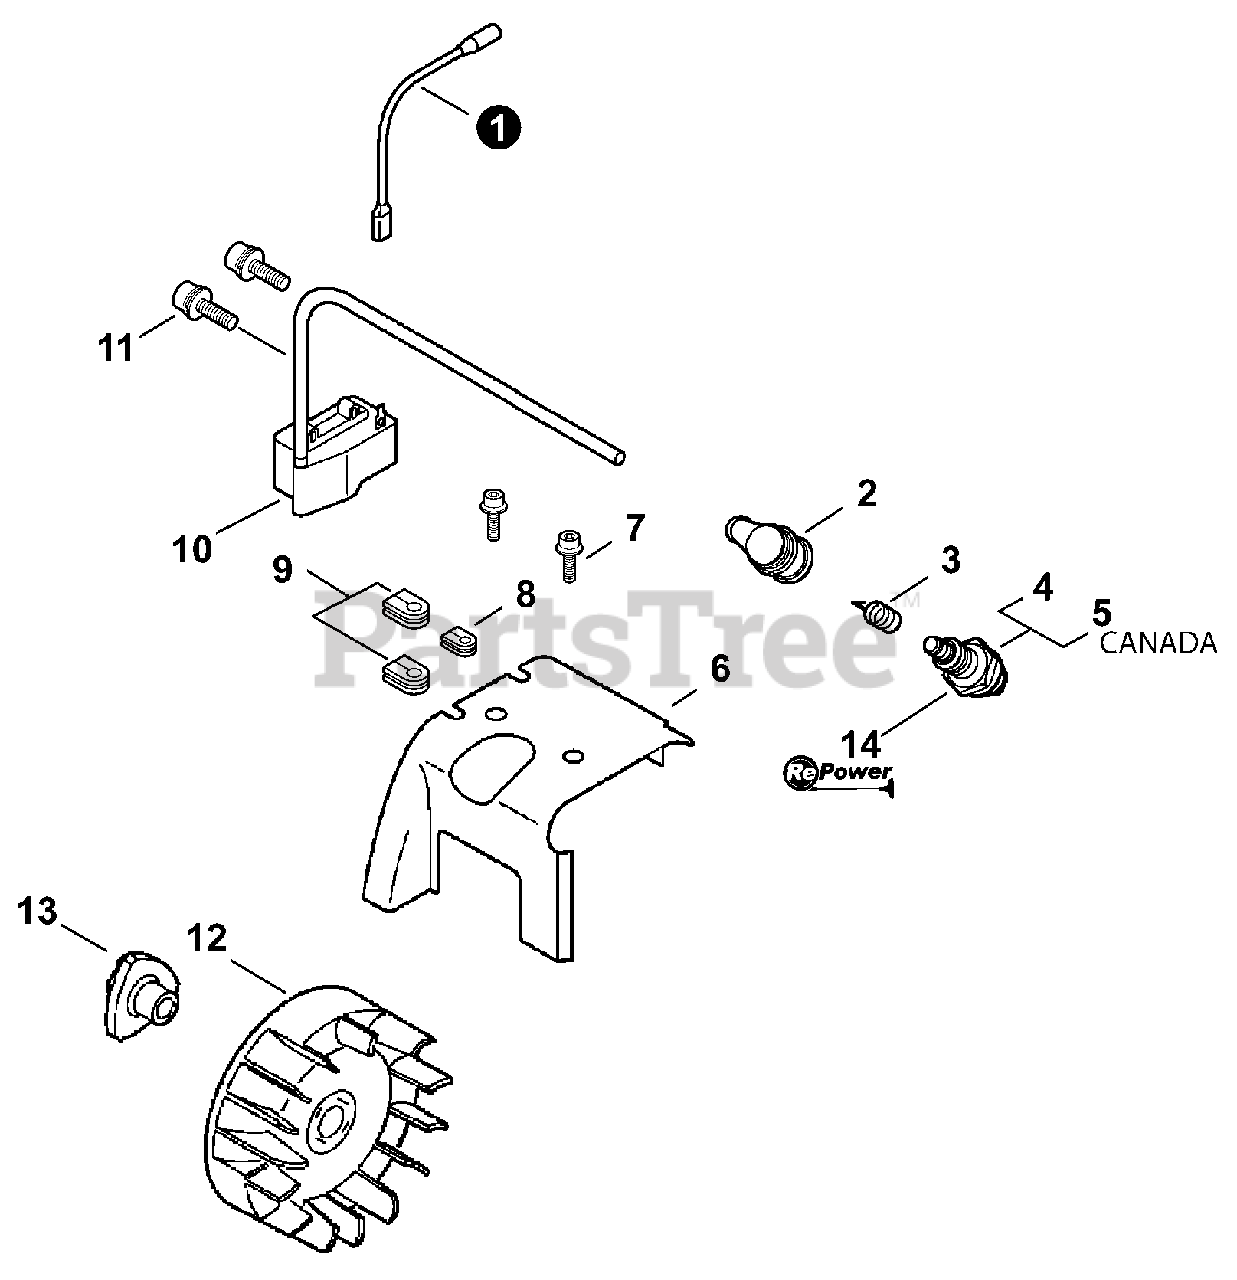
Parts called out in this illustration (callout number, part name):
1	LEAD - IGNITION
2	CAP, SPARK PLUG
3	TERMINAL, SPARK PLUG
4	SPARK PLUG - BPM-8Y
5	SPARK PLUG - BPMR-8Y
6	COVER, CYLINDER
7	BOLT 5×8
9	GROMMET, HT CORD
10	COIL, IGNITION
11	BOLT 4×20
12	FLYWHEEL
13	HUB, FAN
14	TUNE-UP KIT - REPOWER
